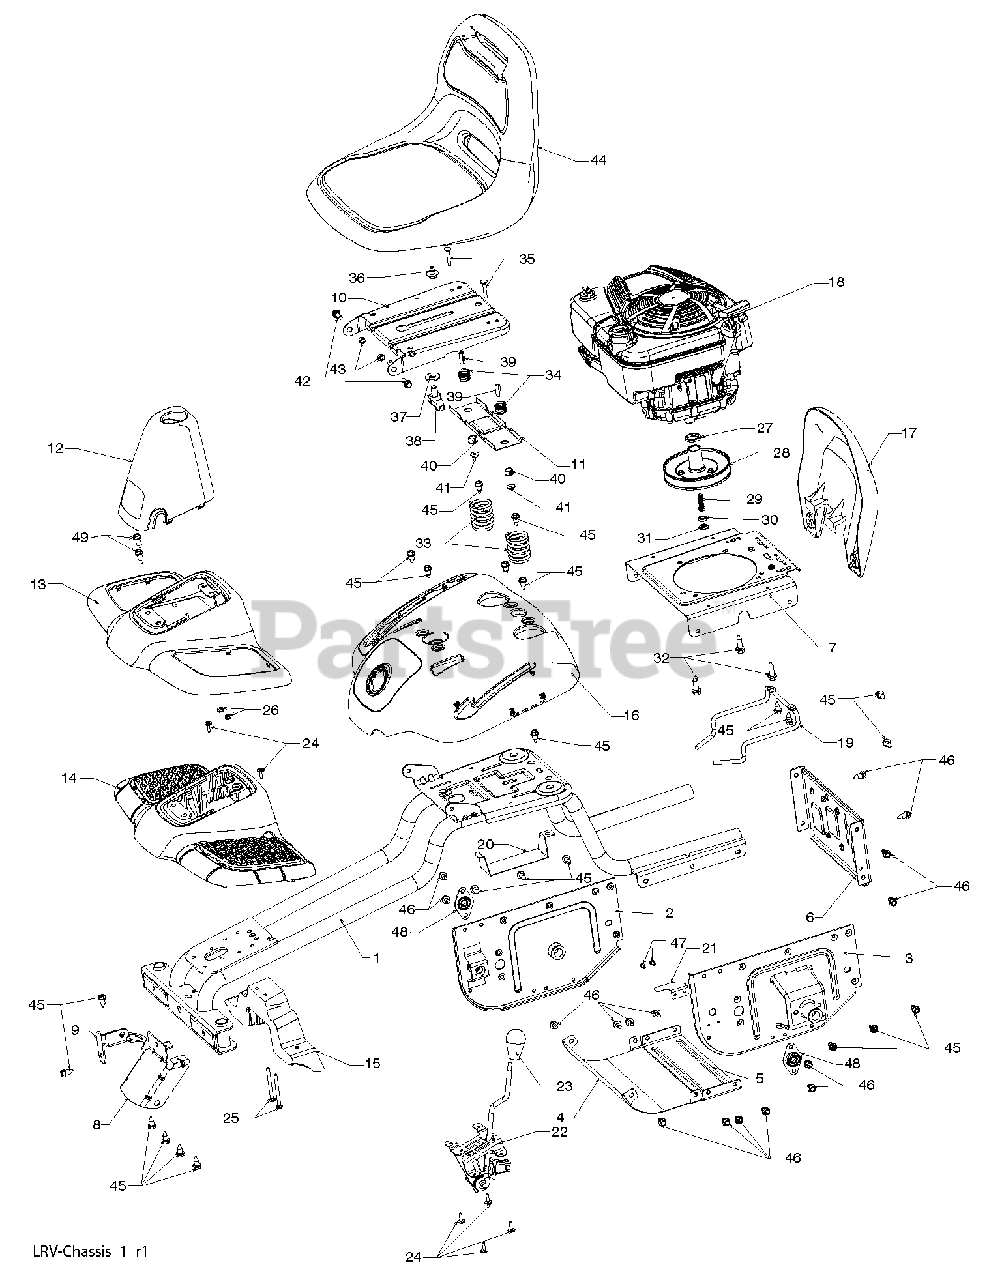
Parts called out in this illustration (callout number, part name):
1	WELDMENT, CHASSIS
2	SUPPORT, AXEL LH
3	SUPPORT, AXEL RH
4	SHIELD, TRANSAXLE FRONT
5	BRACE, AXLE CROSS
6	COVER, FRICTION DRIVE
7	PLATE, ENGINE
8	BRACKET, CHASSIS FRONT
9	BRACKET, STEERING SUPPORT
10	PAN, SEAT
11	BRACKET, SWITCH MOUNTING
12	BOOT, DUST
13	COVER, FOOT REST
14	STRUCTURE, FOOT REST
15	SUPPORT, FOOT REST
16	FENDER, CONTROL
17	GUARD, ENGINE
18	ENGINE (NON-CALIFORNIA)
18	ENGINE (CALIFORNIA)
19	KEEPER, BELT
20	BRACKET, BATTERY
21	LEVER, SWITCH
22	DECK CLUTCH ASM
23	KNOB
24	SCREW, NO. 10
25	BOLT, CARRIAGE 1/4-20 X 3
26	NUT, 1/4-20
27	SPACER, ENGINE
28	DISC, FRICTION ASM
29	BOLT, SCKT HD 3/8-24 X 1 .25
30	BEARING
31	SPACER, NEUTRAL
32	BOLT, 3/8-16 X .280
33	SPRING, SEAT
34	SPRING
35	BOLT, 1/4-20 X 1 1/2
36	BOLT, SHOULDER
37	WASHER, 17/32 X 1 3/16
38	KNOB, SEAT
39	SPACER
40	BUSHING, NYLON SNAP
41	NUT, LOCK
42	BOLT, 5/16-18 SHOULDER
43	NUT, 5/16-18
45	BOLT, 5/16-18 X 3/4
46	BOLT, 5/16-18 X 1/2
47	SCREW
48	BEARING FLANGE BALL
49	SCREW 5/16-18 X1
